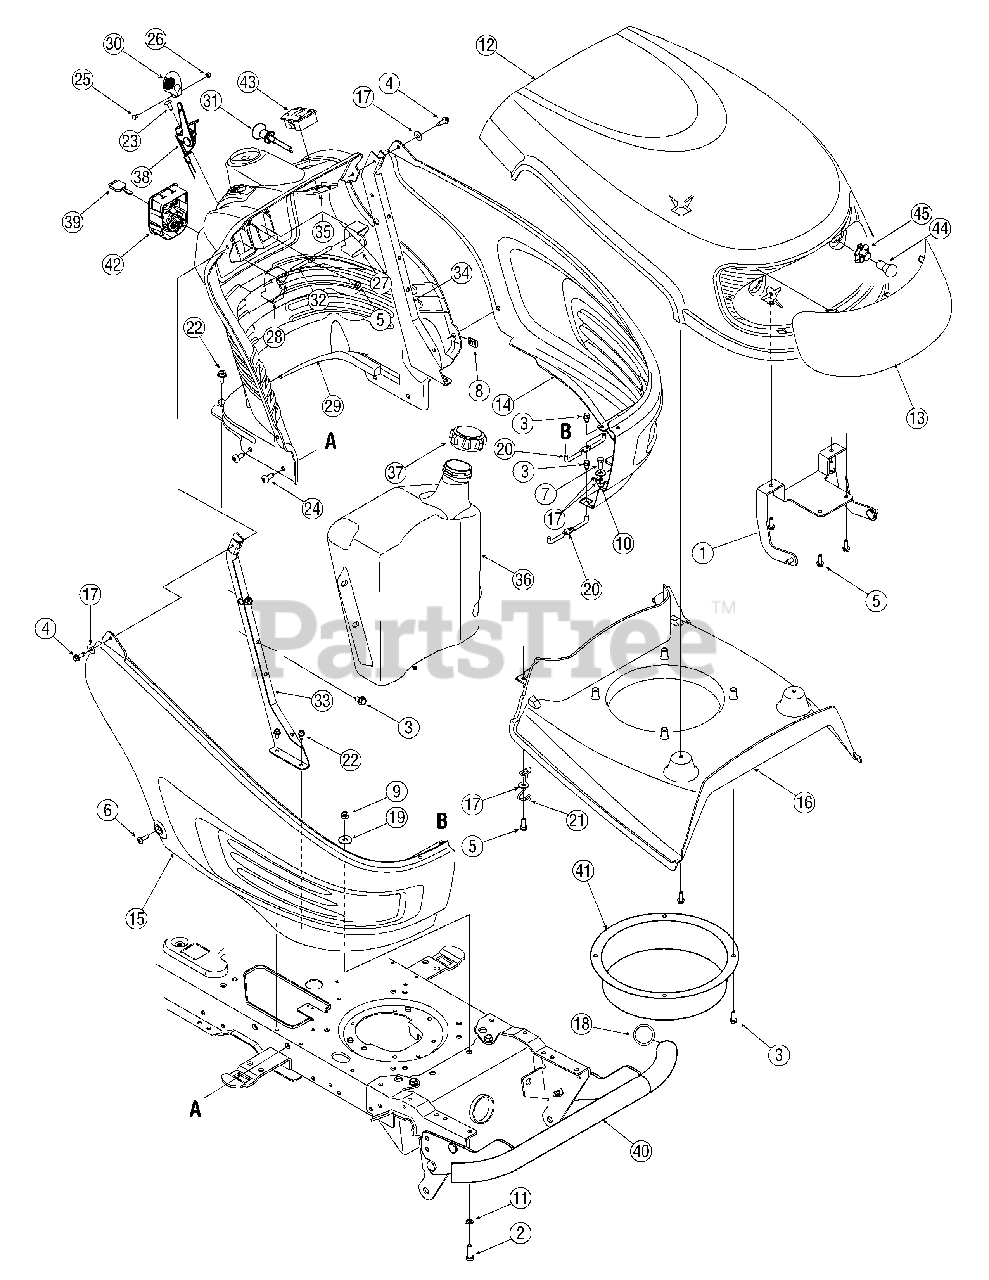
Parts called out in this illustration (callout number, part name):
3	Screw, 1/4-20, 0.625
4	Screw, 1/4-20, 0.750
5	Screw, 1/4-15, 0.750
6	Screw, Machine, 1/4-20, 0.750
7	Hex Screw, 1/4-20,.75, Gr5
8	Nut, Clip, 1/4-20
9	Nut, Flange Lock, 5/16-18, Grf, Nylon
10	Nut, Flange Lock, 1/4-20, Grf, Nylon
11	Nut, Speed,.3125 ID
12	Hood
13	Lens
14	Side Panel, LH
15	Side Panel, RH
17	Washer, Flat,.28 x.74 x.063
19	Washer, Flat,.344 x 1.0 x.063
20	Support, Side Panel
21	Rod, Hood Latch
22	Screw, 5/16-12, 0.750
23	Screw, 1/4-14, 0.625
24	Screw, 5/16-18, 0.750
25	Screw, Machine, #8-32, 0.375
26	Nut, Hex, #8-32
28	Cruise Control Lever
30	Control Knob
31	Choke Knob w/ Cable, 37.5"
32	Rod, Brake / Cruise Pivot
35	Electric PTO Switch
36	Fuel Tank, 3 Gal.
37	Fuel Cap
38	Throttle Cable, 39"
39	Key, Ignition
39	Key w/ Plastic Cover, Ignition
42	Ignition Switch Module
43	Systems Indicator Monitor w/ Hour Meter
44	Miniature Lamp, 12V
45	Socket, Lamp
